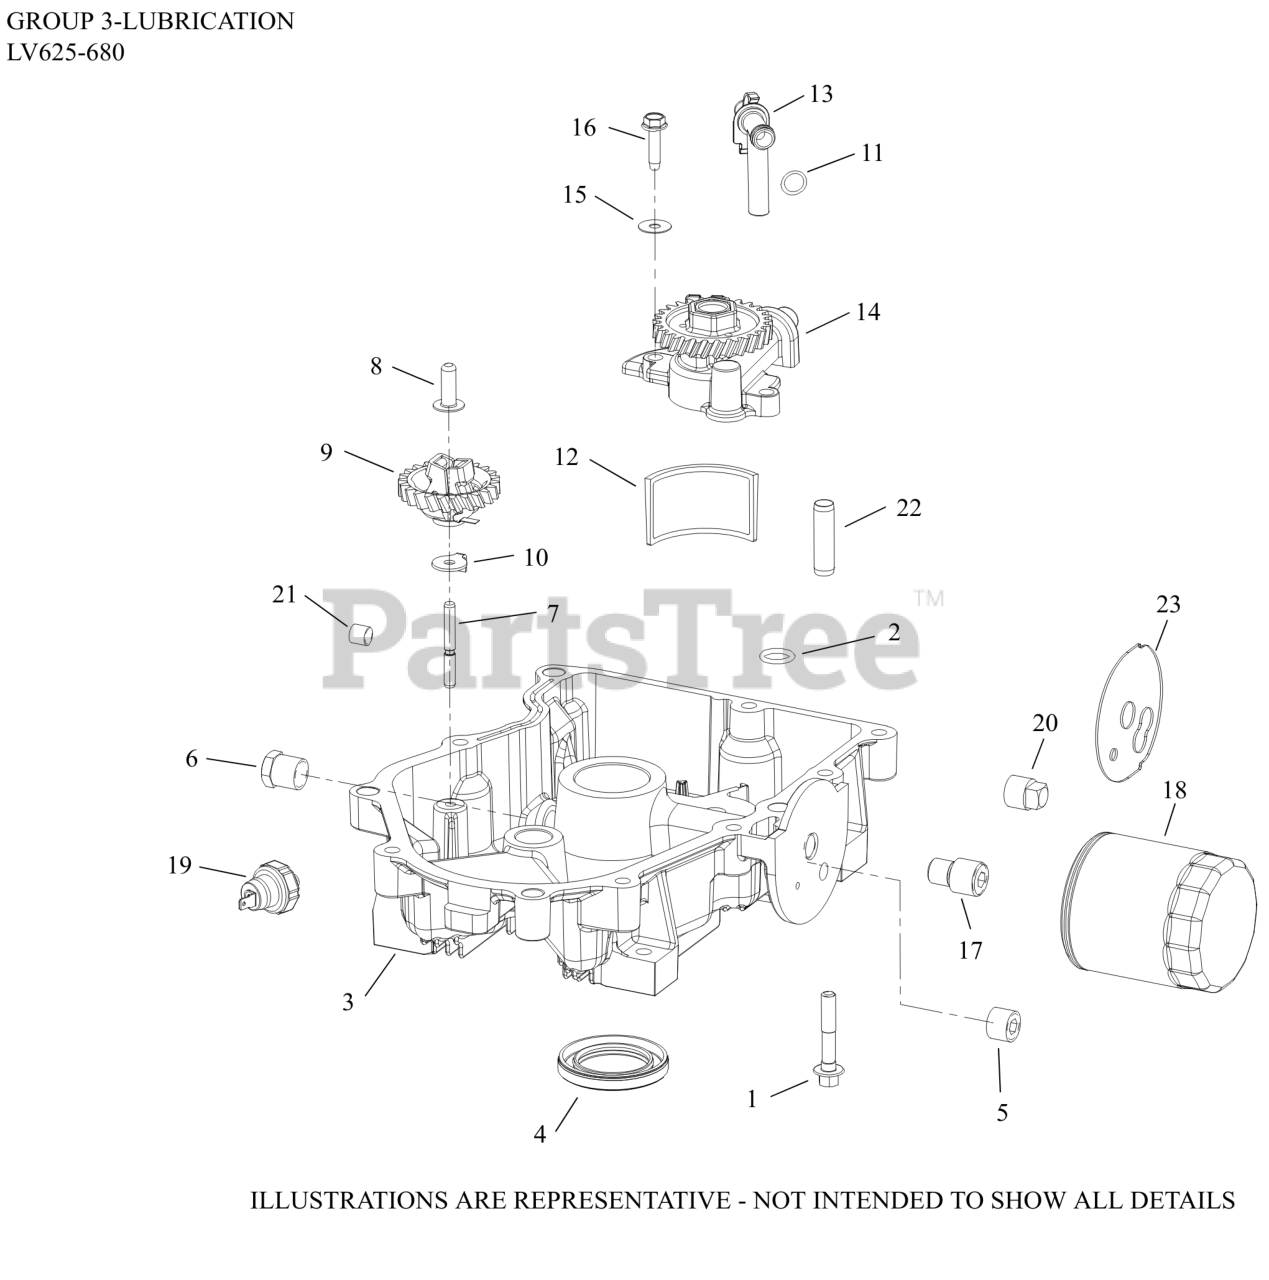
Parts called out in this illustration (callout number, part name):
1	SCREW, FLG M8X1.25X45
3	PAN , OIL ASSEMBLY-(#2419932S)
5	PLUG, PIPE CTSK 3/8"
7	SHAFT, GOVERNOR GEAR
8	PIN, GOVERNOR REGULATING
9	KIT, GOVERNOR GEAR W/PIN
10	TAB, LOCKING
11	O-RING, OIL PICK-UP
12	SCREEN, OIL
13	KIT, OIL PICK-UP TUBE-(#DSC)
14	PUMP ASSEMBLY, OIL-USE 24 393 53-S
15	WASHER, FLAT 6 MM
16	SCREW,FLG THD FRM M6X1.0X25-(#25086395S)
17	NIPPLE, OIL FILTER-(#2413609S)
18	OIL FILTER
20	PLUG, SQ HD PIPE 3/8"
21	PLUG, CTSK PIPE 1/8"
NI	SEALANT(LOCTITE 222 RETAIN CMPND 0.5ML)
